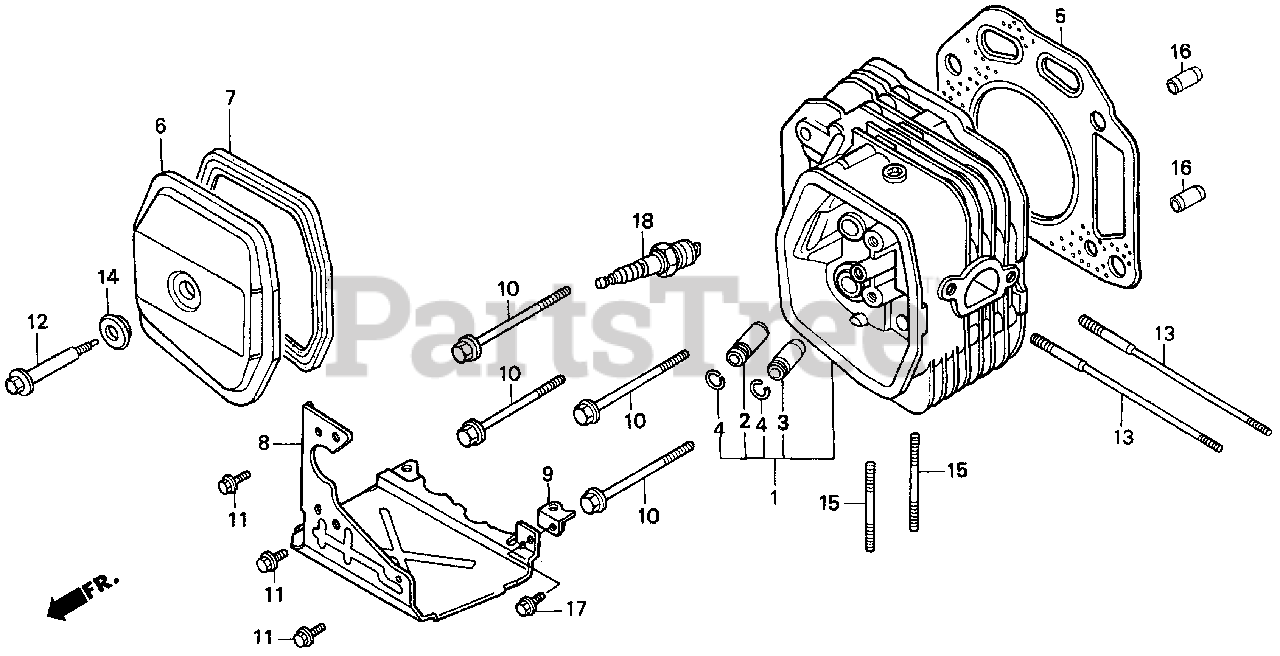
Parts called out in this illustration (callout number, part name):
1	CYLINDER HEAD COMP.
2	GUIDE, VALVE (OS)
3	GUIDE, EX. VALVE (OS)
4	CLIP, VALVE GUIDE
5	GASKET, CYLINDER HEAD
6	COVER, HEAD
7	GASKET, CYLINDER HEAD COVER
10	BOLT, FLANGE (10X85)
12	BOLT, HEAD COVER
13	BOLT, STUD (8X131.5)
14	WASHER COMP., HEAD COVER
15	BOLT, STUD (8X22)
16	PIN A, DOWEL (12X20)
18	SPARK PLUG (BPR5ES) (NGK)
